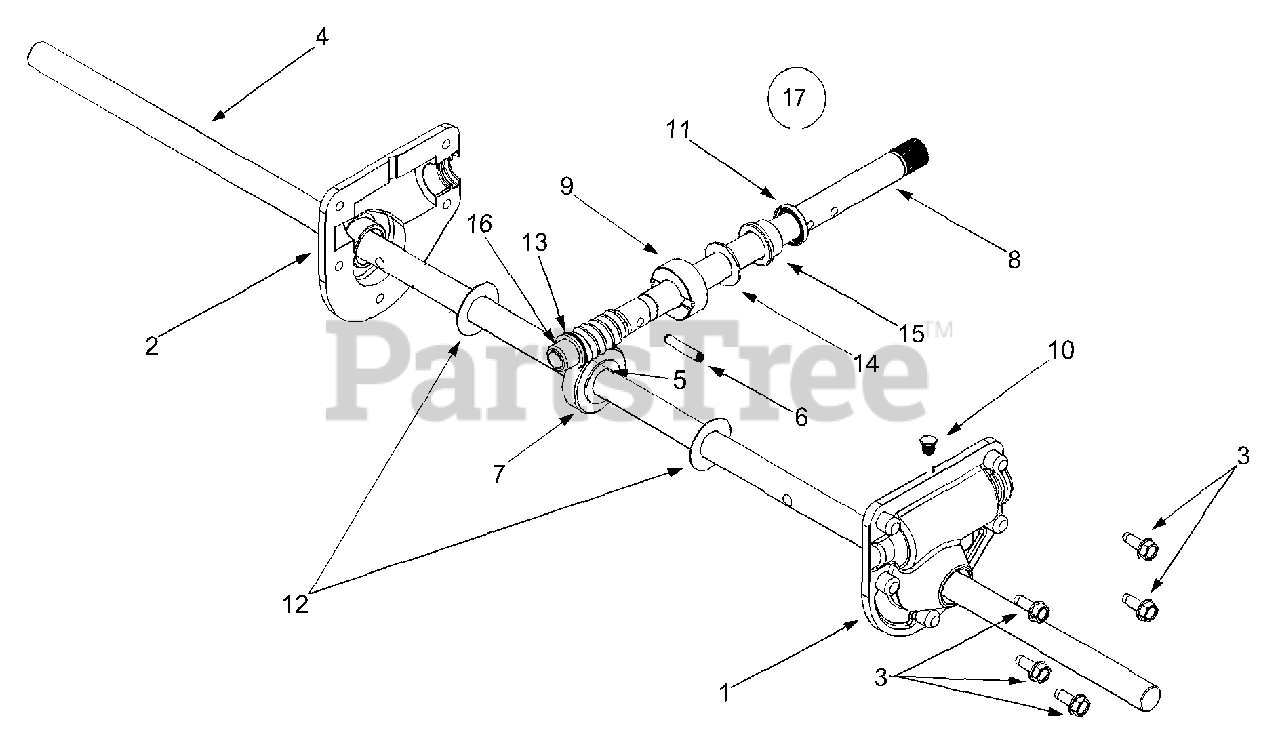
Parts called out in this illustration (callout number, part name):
1	RH Reducer Housing
2	LH Reducer Housing
3	Hex Screw 1/4-20 x .75
4	Spiral Axle 24" E
5	Key
6	Pin-Spiral
7	Worm Gear, 20T
8	Worm Shaft
9	Thrust Collar
10	Grease Plug
11	Grease Seal
12	Flat Washer .76 x 1.5 x .030
13	Flat Washer .508 x 1.0 x .020
14	Flat Washer .76 x 1.5 x .060
15	Flange Bearing .75 x 1.0 x .59
16	Flange Bearing .75 x 1.0 x .925
17	Ass'y. Complete 24" E
